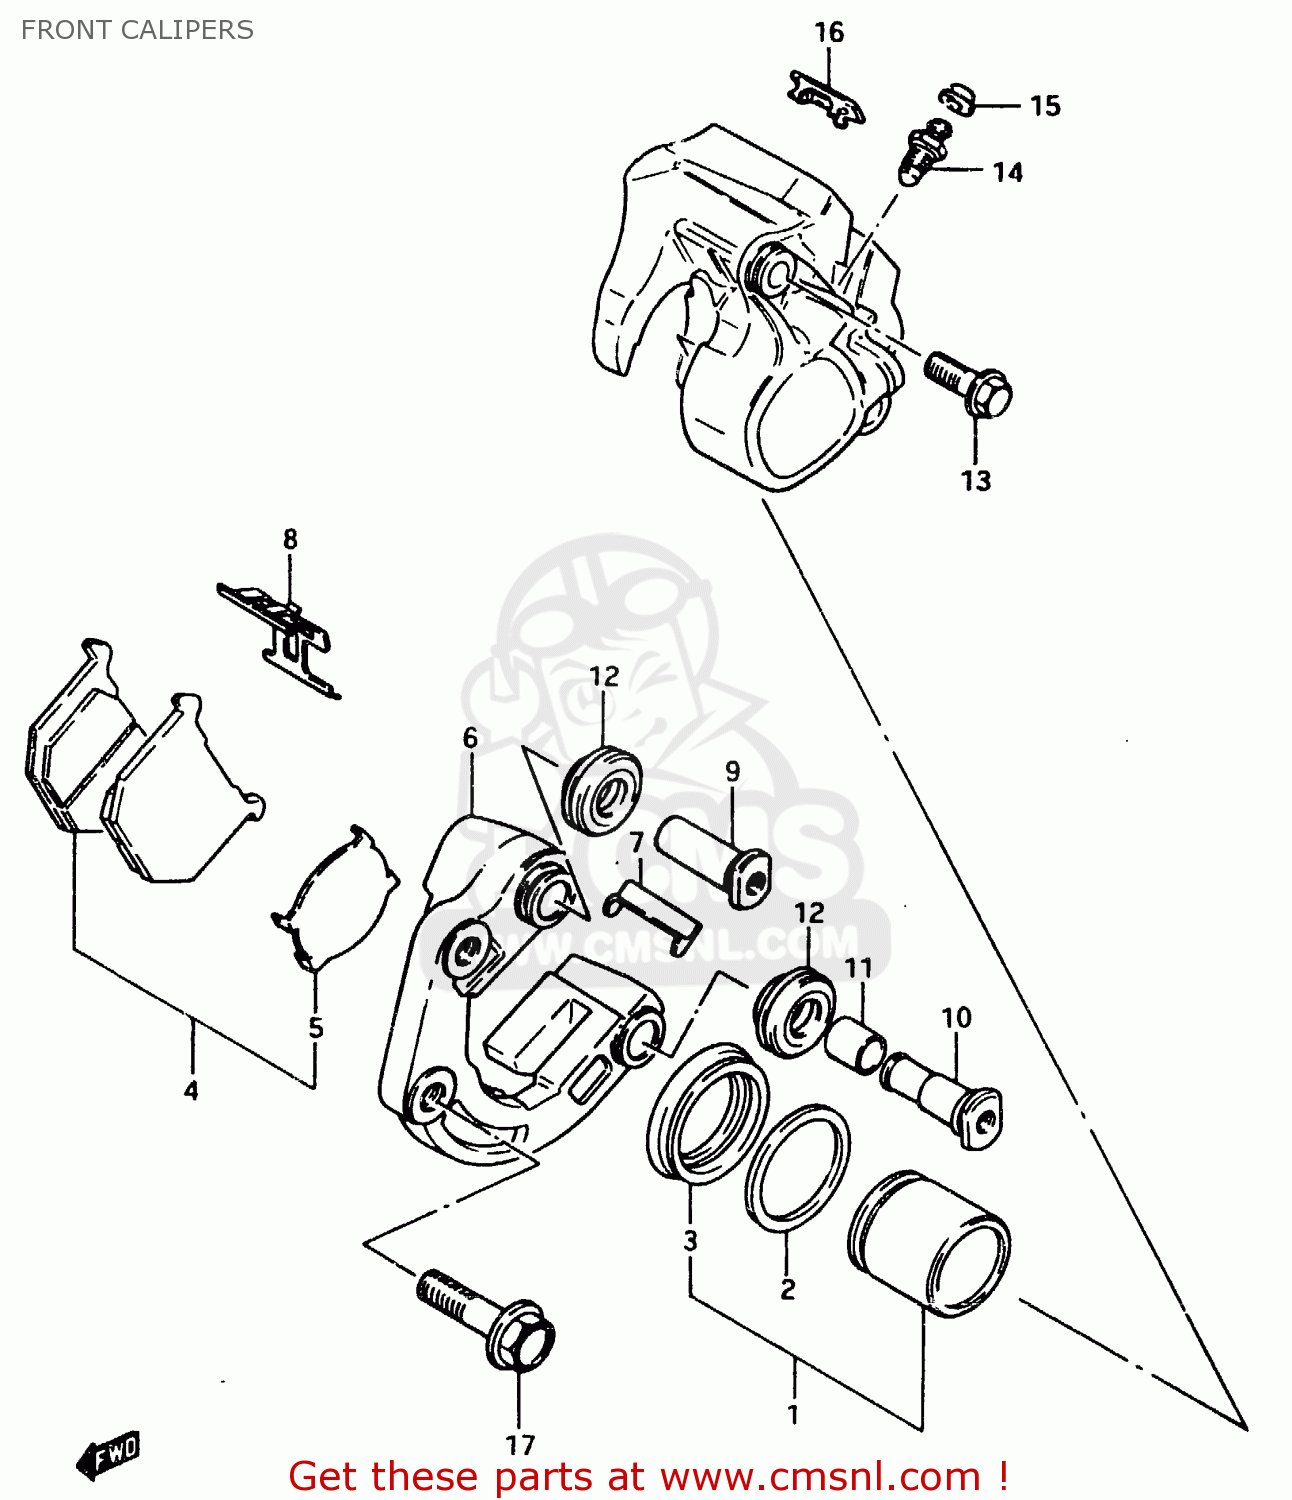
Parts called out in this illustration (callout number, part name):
1	PISTON SET
2	SEAL,PISTON
3	BOOT,PISTON
4	PAD & SHIM SET (NAS)
5	SHIM,PAD
6	CARRIER,CALIPER,LEFT
7	GUIDE,PAD
8	SPRING,PAD
9	AXLE NO.1
10	AXLE NO.2
11	BUSH,AXLE
12	BOOT,AXLE
13	BOLT
14	BLEEDER
15	CAP,BREATHER
16	COVER
17	BOLT 10X40
